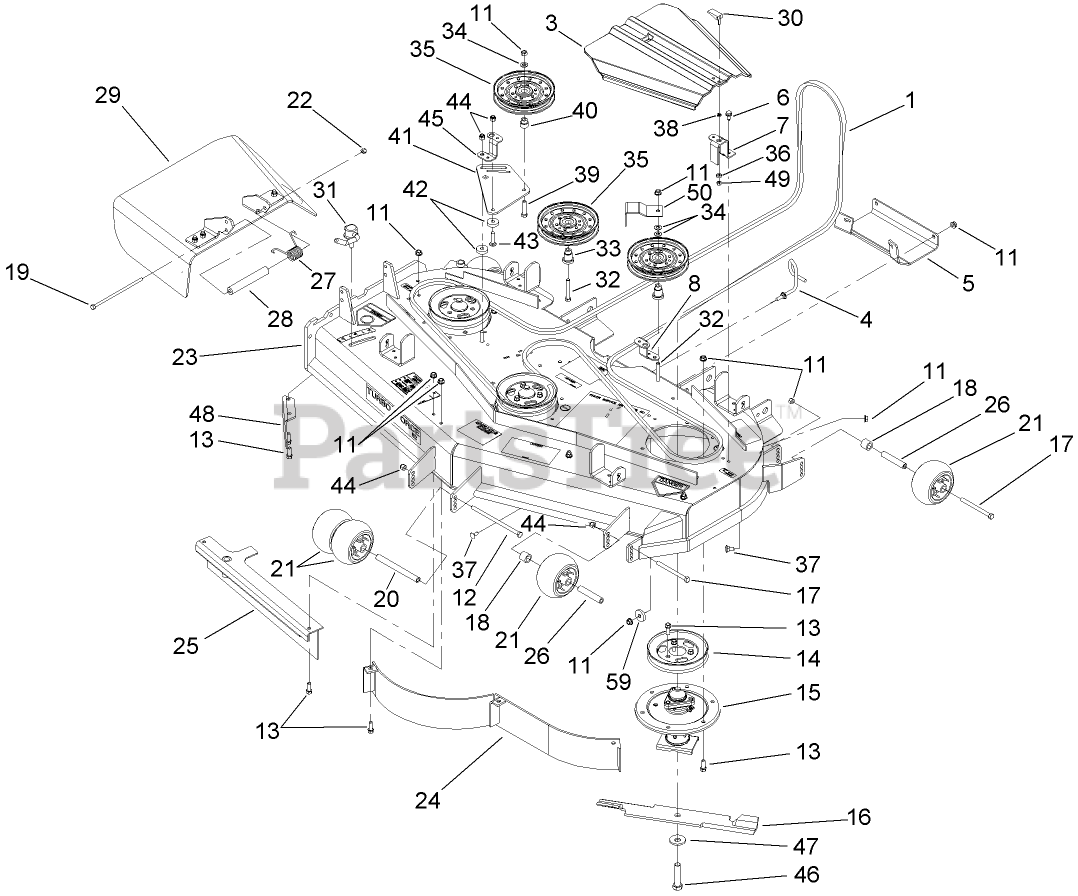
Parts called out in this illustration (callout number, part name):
3	COVER-BELT
4	GUIDE-BELT
5	Plate-Skid
6	SCREW-HWHTF
7	BRACKET-COVER
8	BRACKET-COVER, TALL
11	NUT-HHF, WHIZ
12	SCREW-HH
13	SCREW-HWH
14	Pulley
15	SPINDLE ASM
16	BLADE-18IN, HI FLOW
17	SCREW-HH
18	TUBE-SPACER
19	SCREW-HH
20	SPACER-WHEEL
21	ROLLER-SCALP, ANTI
22	NUT-LOCK, NI
23	DECK ASM
26	TUBE-SPANNER
27	SPRING-TORSION
28	SPACER
29	RUBBER DEFLECTOR ASM
30	HANDLE-LATCH, SWELL
31	LEVER ASM
32	SCREW-HH
33	MOUNT-PULLEY
34	WASHER-FLAT
35	Idler-Flat
36	BUSHING-LATCH, SWELL
37	SCREW-CARR
38	WASHER
39	SCREW-HH
40	BUSHING-IDLER
41	Plate-Idler
42	Spacer
43	SCREW-CARR
44	NUT-LOCK, NI
45	BRACKET-COVER, SHORT
46	Screw-Cap
47	Washer-Blade Bolt, Heavy
48	BAFFLE-DISCHARGE
49	NUT-LOCK, HH
50	GUIDE-BELT
59	WASHER
